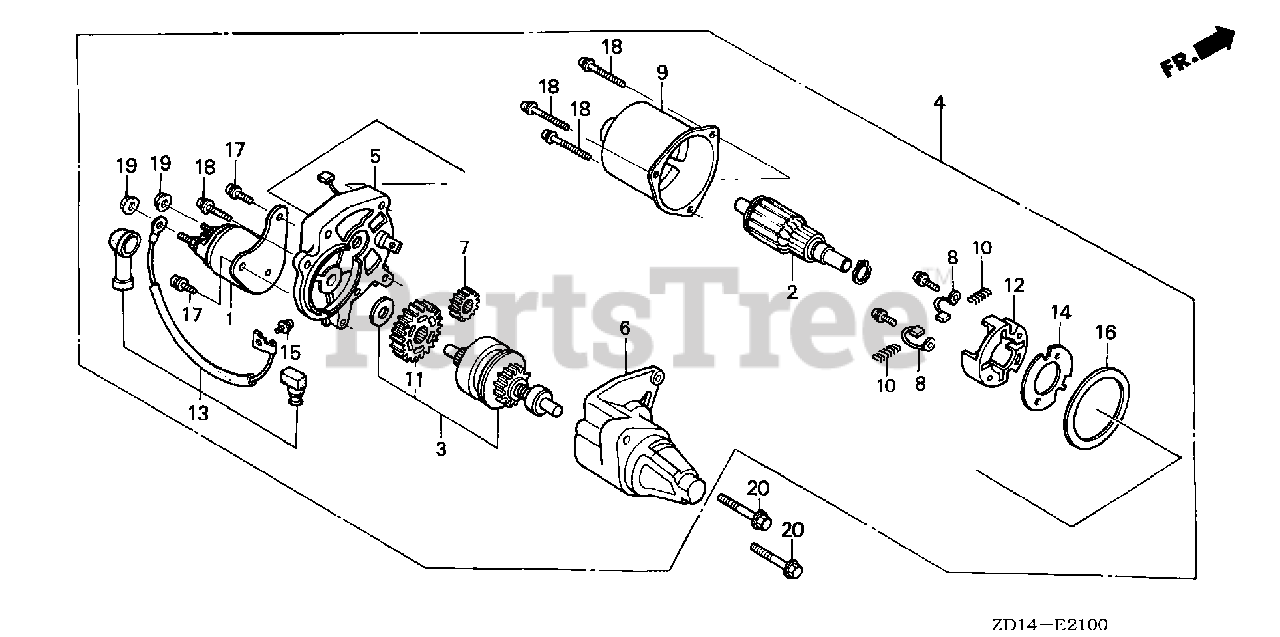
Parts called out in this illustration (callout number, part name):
1	CONTACTOR ASSY.
3	CLUTCH, OVERRUNNING
4	STARTER MOTOR UNIT
5	BRACKET, CENTER
6	BRACKET, FR.
7	GEAR, DRIVE PINION
10	SPRING, BRUSH RETURN
11	GEAR, REDUCTION
12	HOLDER, BRUSH
13	WIRE, WATER COVER
15	SCREW-WASHER (4X6)
17	BOLT-WASHER (5X14)
17	SCREW-WASHER (5X14)
18	SCREW-WASHER (5X3)
19	NUT-WASHER (6MM)
20	BOLT, FLANGE (8X35)
